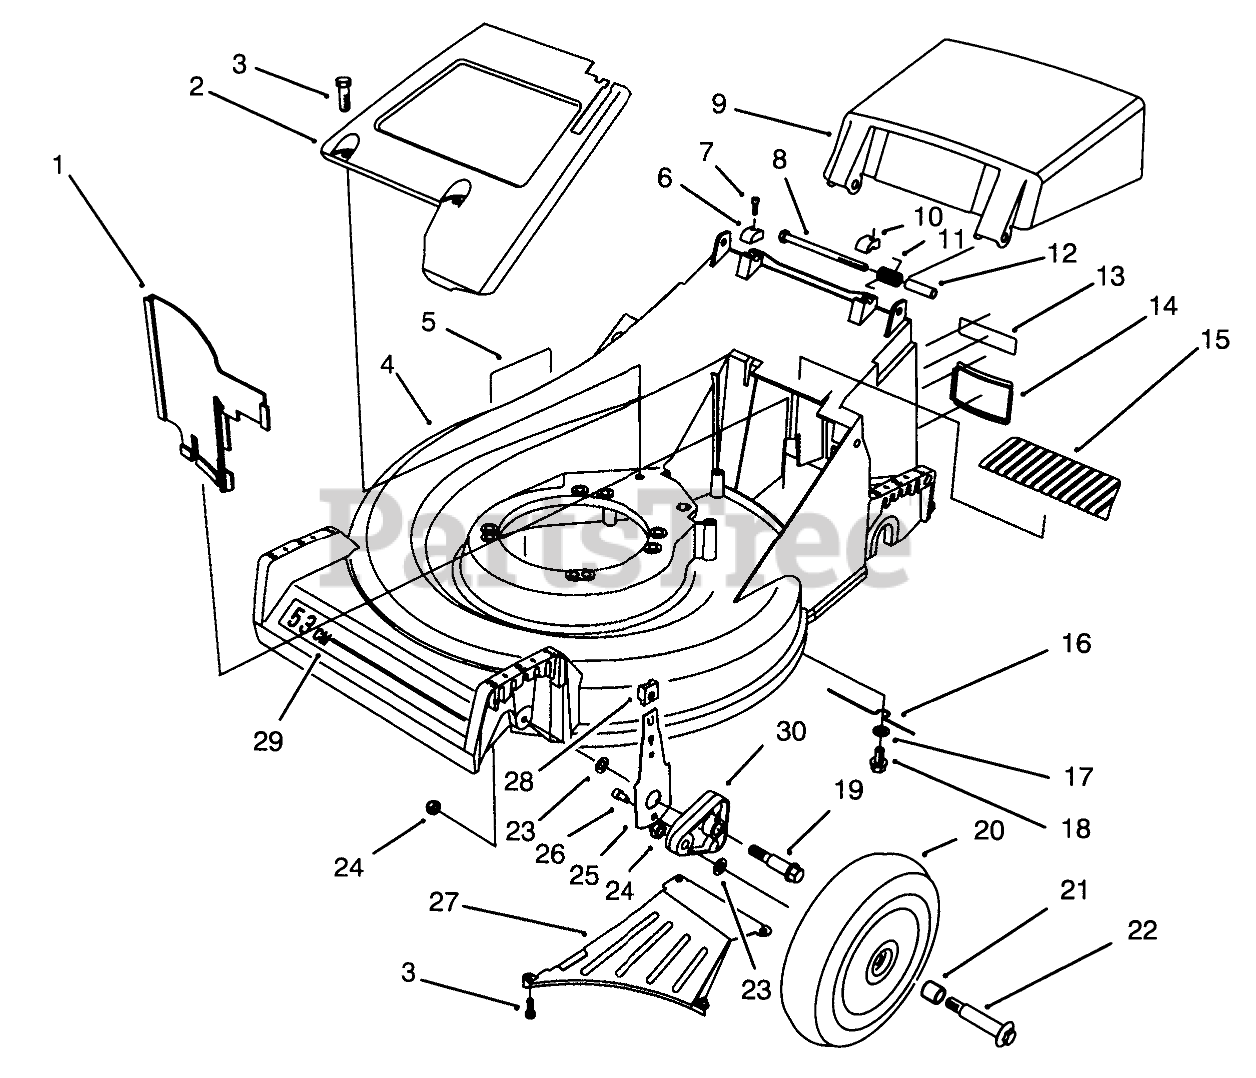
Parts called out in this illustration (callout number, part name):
1	PANEL-VERTICAL
2	PaneI-Screen
3	SCREW-HWHTF
4	Housing-53cm (Incl. Ref. #5 & 29)
5	DECAL - DIN/DANGER
6	CAP-HINGE BOLT, RH
7	SCREW-HSH
8	SCREW-HH
9	Door Discharge
10	CAP-HINGE BOLT, LH
11	SPRING-DOOR
12	SPACER-DOOR
13	DECAL FRENCH REGUL.
14	COVER-ACCESS
15	COVER-TOP
16	RETAINER-BELT
17	WASHER-FLAT
18	SCREW-HHFTF
19	BOLT-SHOULDER
20	Wheel & Tire Assembly (Incl. Ref. #21)
21	BUSHING
22	WHEEL BOLT
23	WASHER
24	NUT-LOCK
25	FRONT SPRING ARM ASM
26	SCREW-HSH, THREAD FORMING
27	Ramp-Discharge
28	KNOB-ARM
29	DECAL
30	ARM-PIVOT, FRONT
